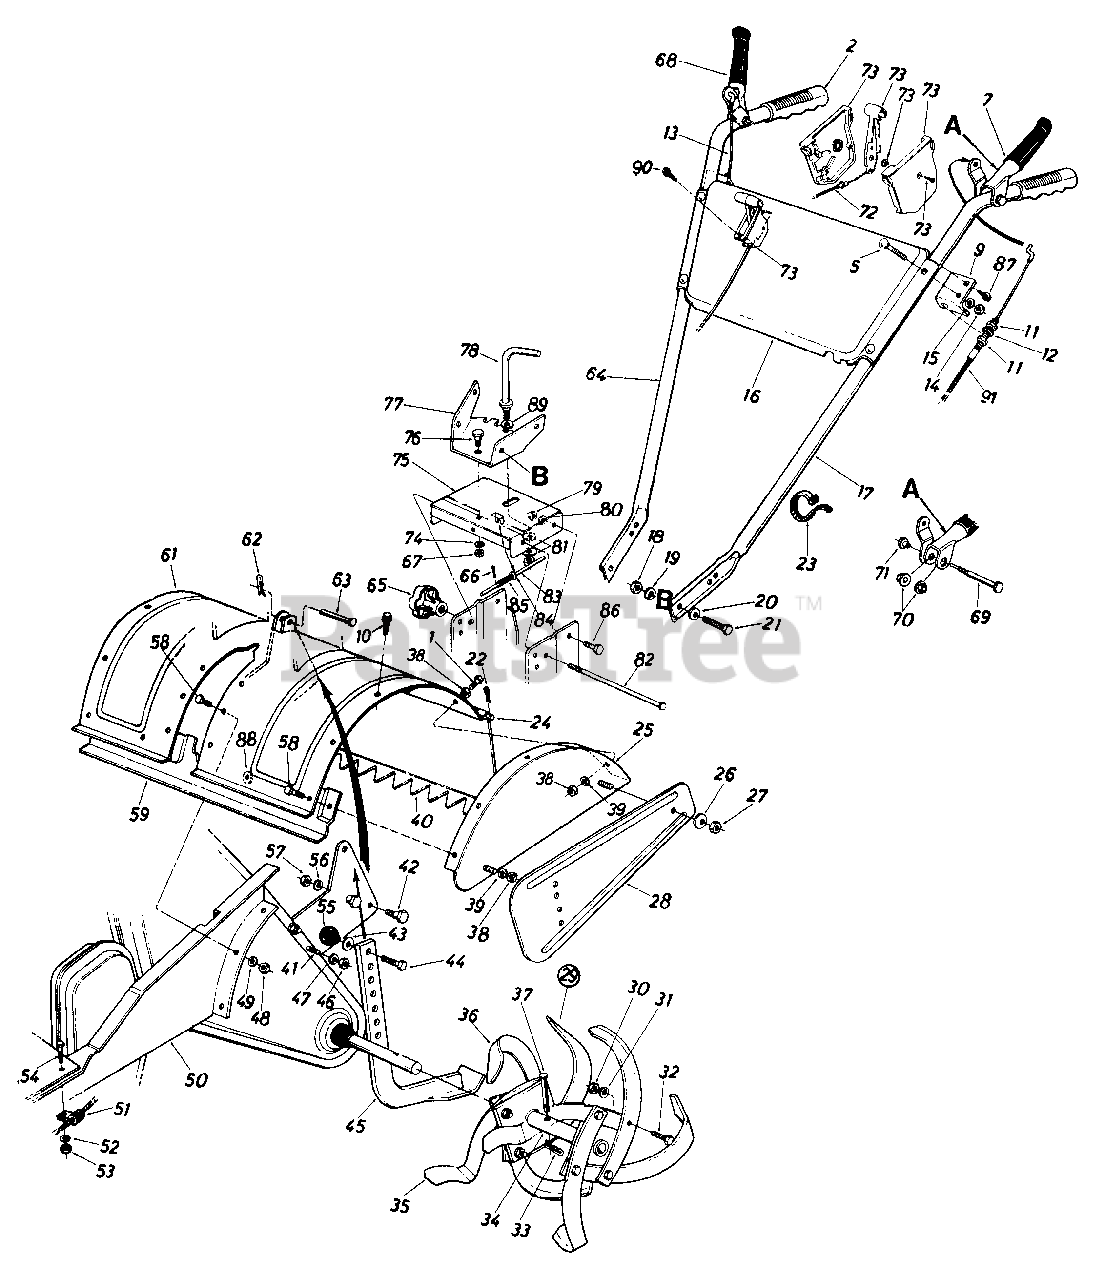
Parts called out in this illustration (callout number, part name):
1	Hex Bolt 5/16-18 x 11/4" Lg.
2	Grip
5	Carr. Bolt 5/16-18 x 1.75"
7	Clutch Grip Ass'y. L.H.
9	Clutch Cable Bracket
10	Hex Wash. S-Tap Scr. 5/16-18 x .62" Lg.
11	Hex Nut 5/16-24 Thd.
12	L-Wash. 5/16" I.D.*
13	Wheel Drive Cable
14	Hex Nut 5/16-18 Thd.
15	L-Wash. 5/16" I.D.
16	Handle Panel
17	Handle L.H.
18	Hex Nut 3/8-16 Thd.
19	L-Wash. 3/8" I.D.
20	Bell-Wash. 3/8" I.D.
21	Hex Bolt 3/8-16 x 1.00" Lg.*
22	Cotter Pin 3/32" Dia. x 3/4"
23	Cable Tie
24	Tiller Flap Rod
27	Hex Nut 5/16-18 Thd.
31	L-Wash. 3/8" I.D.
32	Hex Bolt 3/8-24 x 1.25" Lg.
33	Hairpin Cotter
38	Hex Nut 5/16-18 Thd.
39	L-Wash. 5/16" I.D.
41	Hex Bolt 5/16-18 x 1.0" Lg.
42	Shld. Bolt 1/2" Dia. x .426"
43	Fl-Wash. 3/8" I.D. x 5/8" O.D.
44	Hex Bolt 3/8-16 x 3/4" Lg.
46	Hex Nut 5/16-18 Thd.
47	L-Wash. 5/16" I.D.
48	Hex Nut 5/16-18 Thd.
49	L-Wash. 5/16" I.D.
52	L-Wash. 5/16" I.D.
53	Hex Nut 5/16-18 Thd.
54	Hex Bolt 5/16-18 x 314" Lg.
55	Ball Knob 1-1/4" Dia.
56	L-Wash. 3/8" I.D.
57	Hex Nut 3/8-16 Thd.
58	Hex Bolt 5/16-18 x .75" Lg.
63	Clevis Pin 3/8" Dia.
64	Handle R.H.
65	Hand Knob
66	Cotter Pin 1/16" Dia. x .75" Lg.
67	Hex Cent. L-Nut 3/8-16 Thd.
68	Clutch Grip Ass'y. R.H.
69	Shoulder Bolt .38" Dia. x 1.53" Lg.
70	Hex Flange Plastic Bearing
71	Shoulder Nut 1/4-20 Thd.
72	Throttle Control Wire
73	Throttle Control Box Ass'y.
74	Bell-Wash. .40" I.D.
79	Hex Cent. L-Nut 3/8-16 Thd.
80	Bell-Wash. .40" I.D. x .88" O.D.
81	Bell-Wash. 1/2" I.D. x 1.00" O.D.
82	Lock Pin 5/16" Dia. x 8"
83	Lower Sliding Ass'y.
84	Fl-Wash. .291" I.D. x .62" O.D.
85	Compression Spring .36" O.D. x 1.00" Lg.
86	Shoulder Bolt 1/2" Dia. x .170" Lg.
87	Hex Wash. S-Tap Scr. 1/4-20 x .50" Lg.
88	Bell-Wash. 5/16" I.D.
89	Fl-Wash. 5/8" I.D.
90	Self-Tap Scr. #10 x 1/2" Lg.
91	Tine Control Cable
14979-0498	Rear Tine Shield - OLD CUB YELLOW (0498)
14979-0638	SHIELD-REAR TINE - MTD/TROY-BILT RED (0638)
14979-0665	SHIELD-REAR TINE - YARDMAN GREEN (0665)
